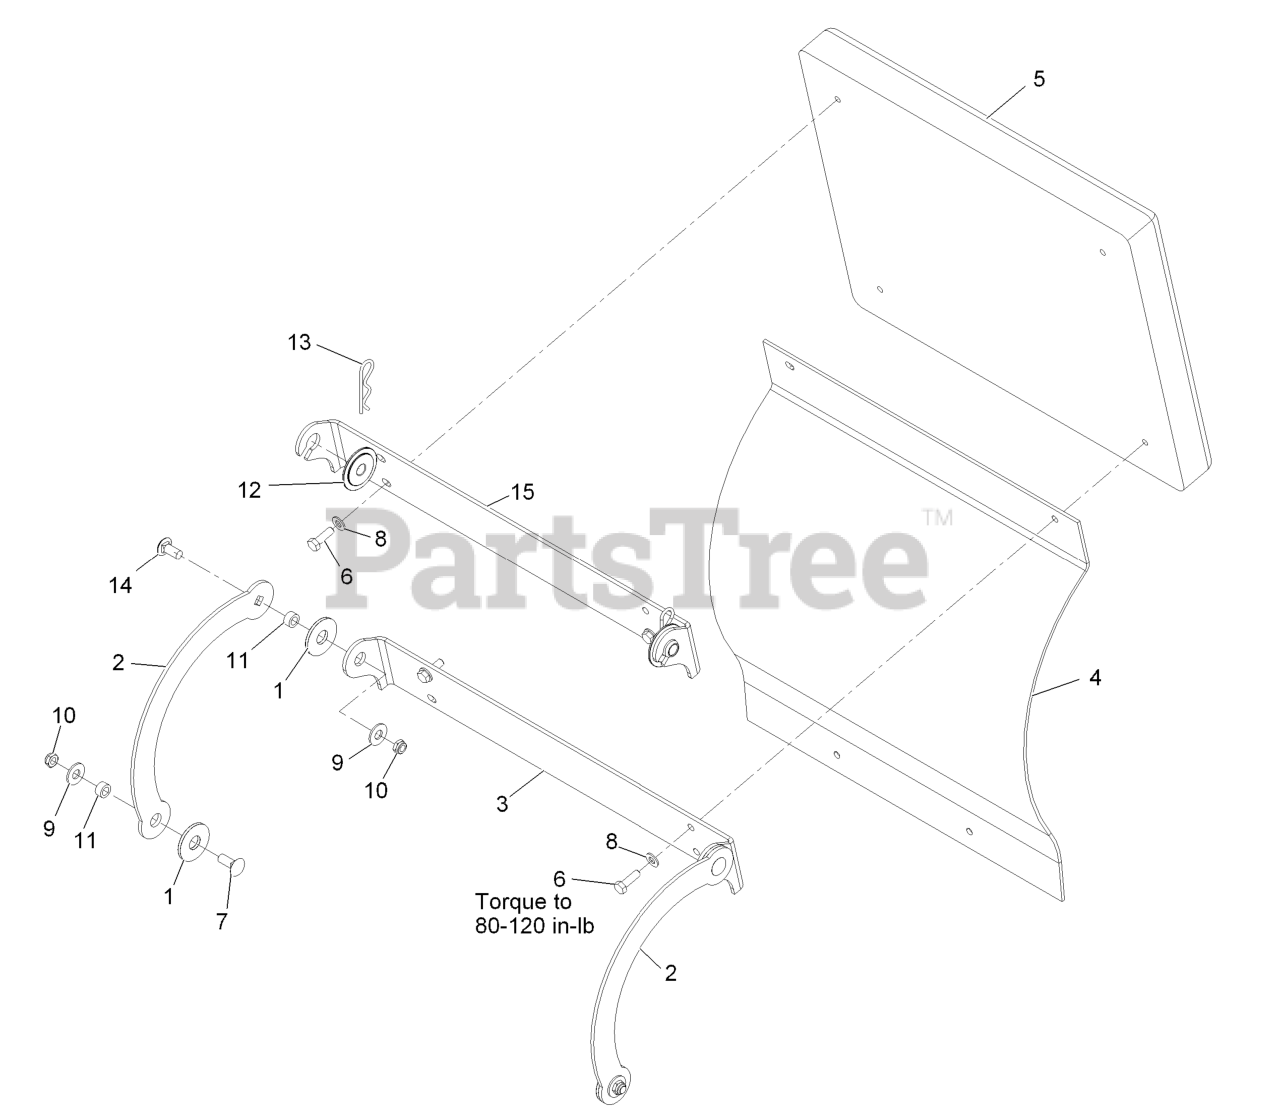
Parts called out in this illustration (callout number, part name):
1	WASHER-FRICTION, COMPOSIT
3	HINGE-PAD
5	PAD,GREY CUSHION
6	SCREW-HH, THREAD LOCKING
7	BOLT-CARR
8	WASHER-PLAIN
9	WASHER-FLAT
11	SPACER
12	SLIDE-BUSHING
13	PIN-HAIR
14	SCREW-CARR
15	HINGE-PAD
